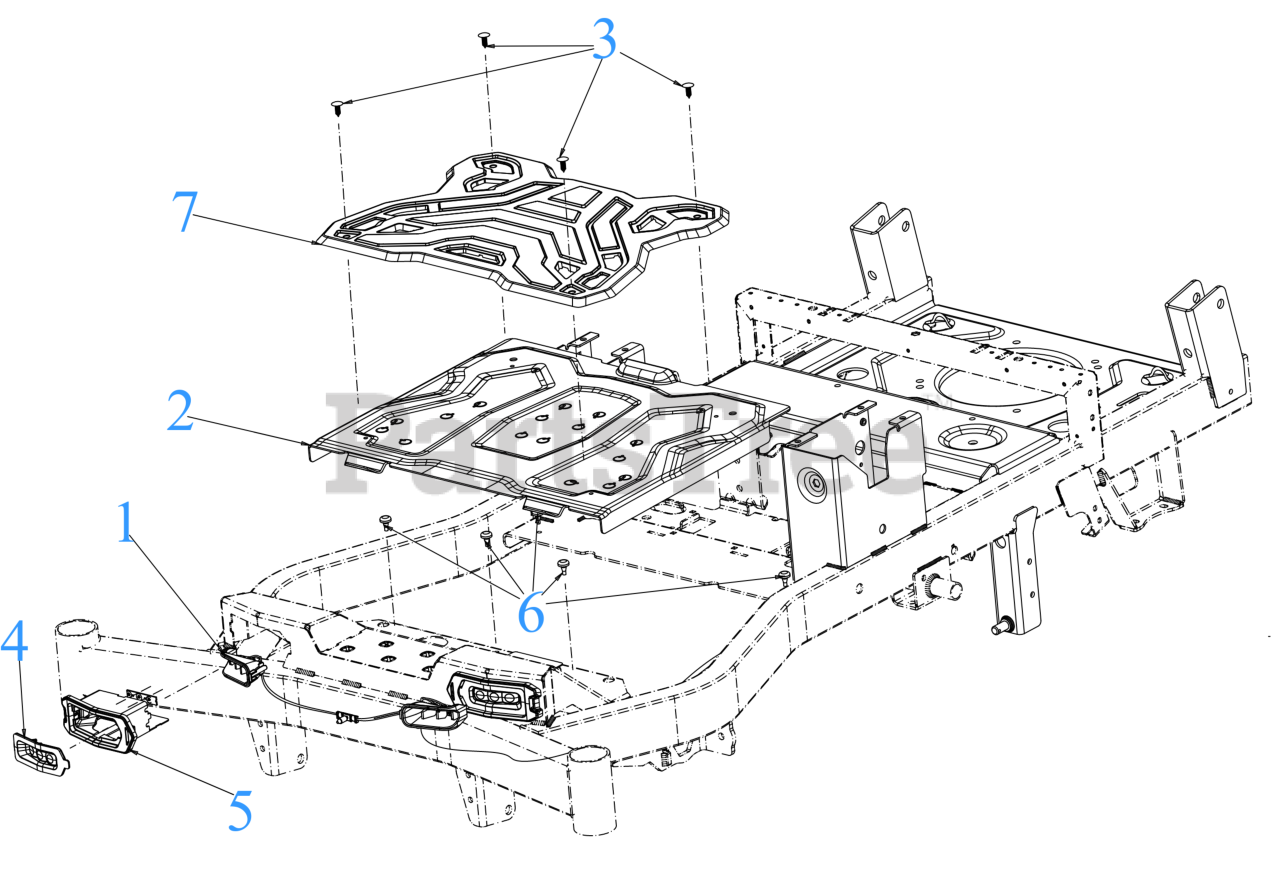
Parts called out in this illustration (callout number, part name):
1	HEADLIGHT HARNESS (W/LED)
2	FLOORBOARD
3	RATCHET CLIP .250
4	LED HEADLIGHT LENS
5	LED HEADLIGHT HOUSING
6	RUBBER BUMPER
7	FLOORBOARD MAT
